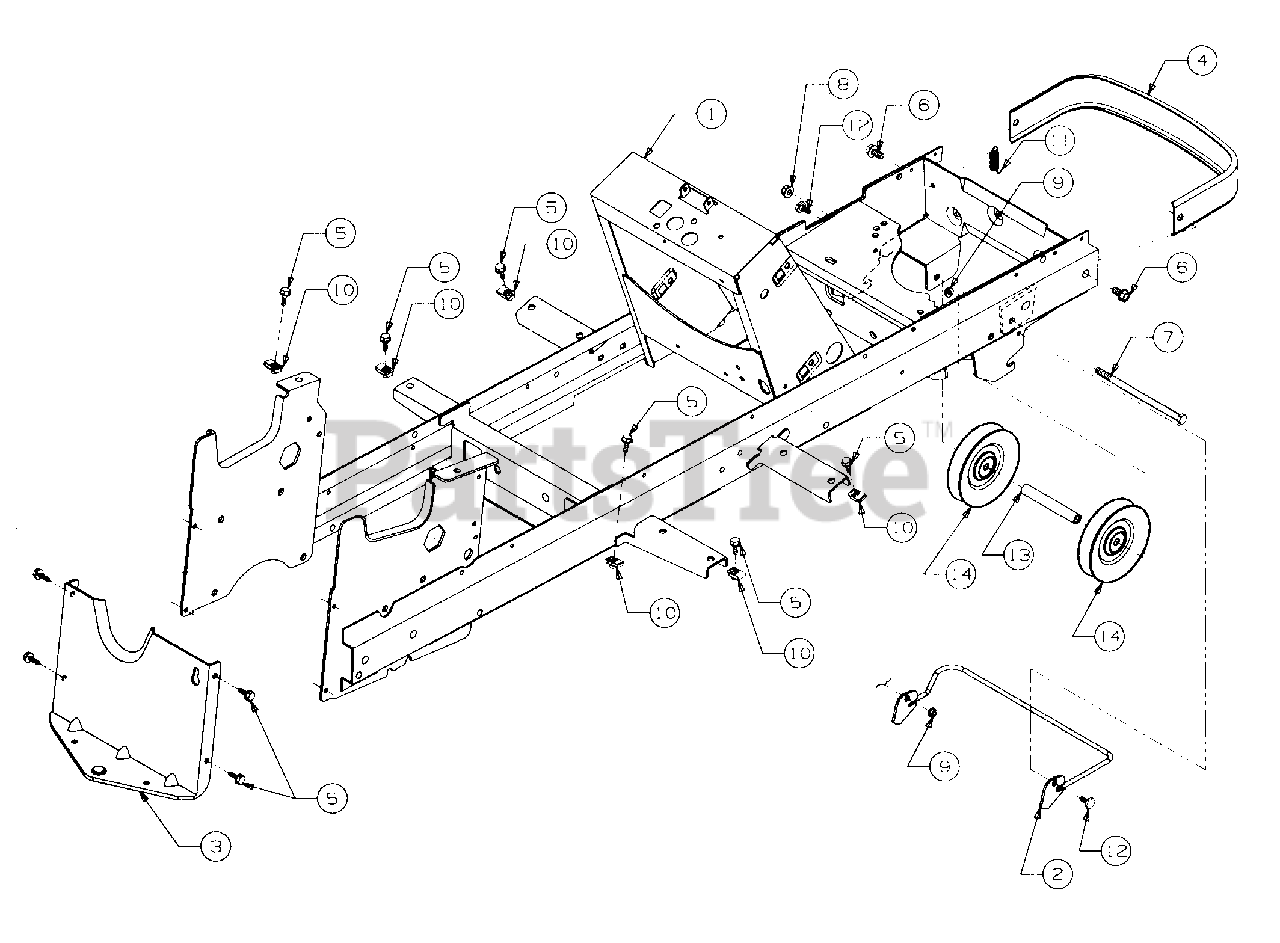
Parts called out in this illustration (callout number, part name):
6	Screw, Hex Wash Tapp 3/8-16 x .75 Lg
7	Screw, Hex Cap, 3/8-16 x 7.0 Lg
8	Nut, Hex Flanged Lock, 3/8-16
9	Nut, Hex Flange Lock, 1/4-20
10	U-Nut, 5/16-18
11	Spring, Latch
12	Bolt, Shoulder
13	Spacer, Idler, .407 ID x .62 OD x 4.38 Lg
14	Pulley, Idler
